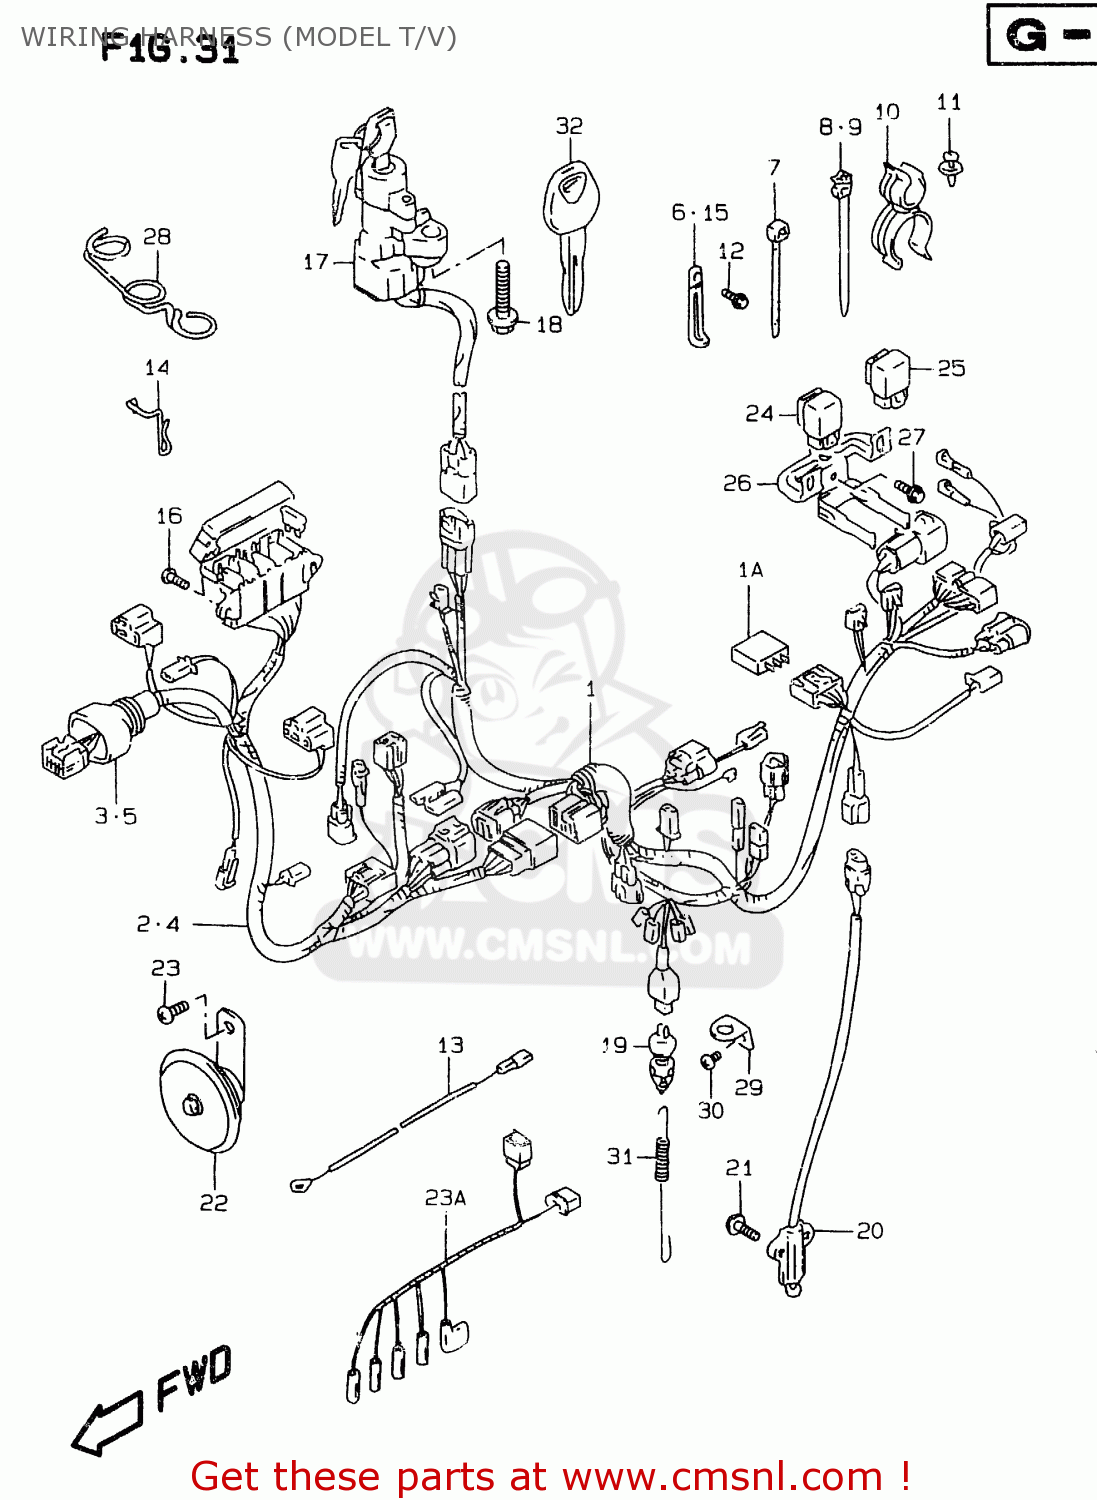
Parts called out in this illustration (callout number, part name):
1	HARNESS,WIRING NO.1
1A	DIODE(STANLEY DE8804)
2	HARNESS,WIRING NO.2
3	COVER,SPEEDOMETER COUPLER
4	HARNESS, WIRING NO. 2
5	COVER,SPEEDOMETER COUPLER
6	CLAMP(L:45)
7	CLAMP(L:95)
8	CLAMP
9	CLAMP L:165
10	CLAMP
11	CLIP(BLACK)
12	BOLT
13	WIRE,OIL PRESSURE SWITCH LEAD
14	STOPPER,FUSE BOX
15	CLAMP(L:80)
16	SCREW
17	LOCK ASSY,STEERING
18	BOLT(8X20)
19	SWITCH ASSY,STOP LAMP
20	SWITCH ASSY,SIDE STAND WARNING
21	BOLT 6X20
22	HORN ASSY
23	SCREW(8X14)
23A	WIRE,CARB HEATER
24	RELAY ASSY
25	RELAY ASSY
26	BRACKET,SIDE STAND RELAY
27	BOLT
28	GUIDE,WIRING HARNESS
29	BRACKET,STOP LAMP SWITCH
30	SCREW
31	SPRING
32	KEY,BLANK
